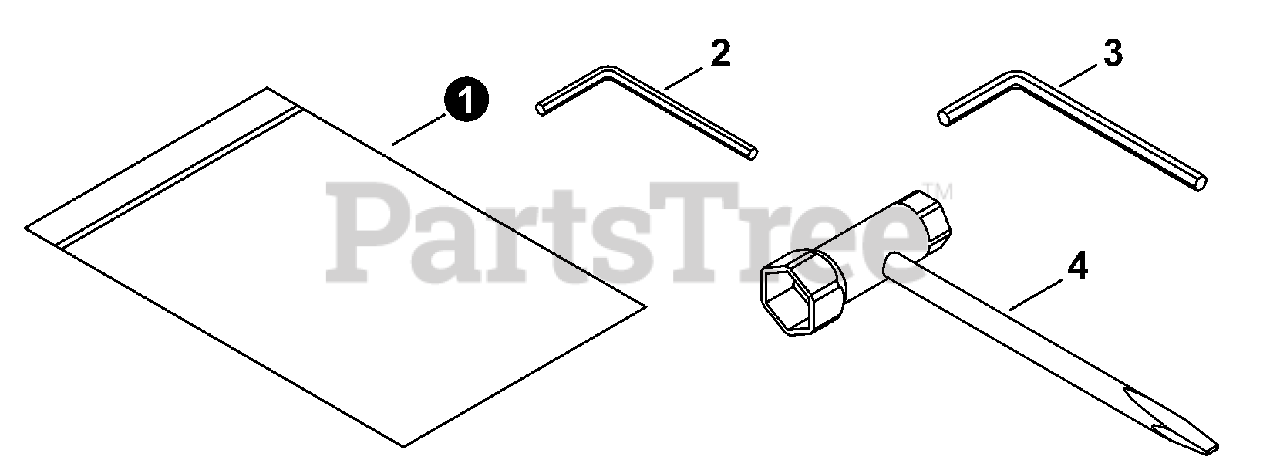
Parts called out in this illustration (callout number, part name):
1	BAG, TOOL
2	WRENCH, ALLEN 4 MM
3	WRENCH, ALLEN 5 MM
4	T-WRENCH 17×19 MM
